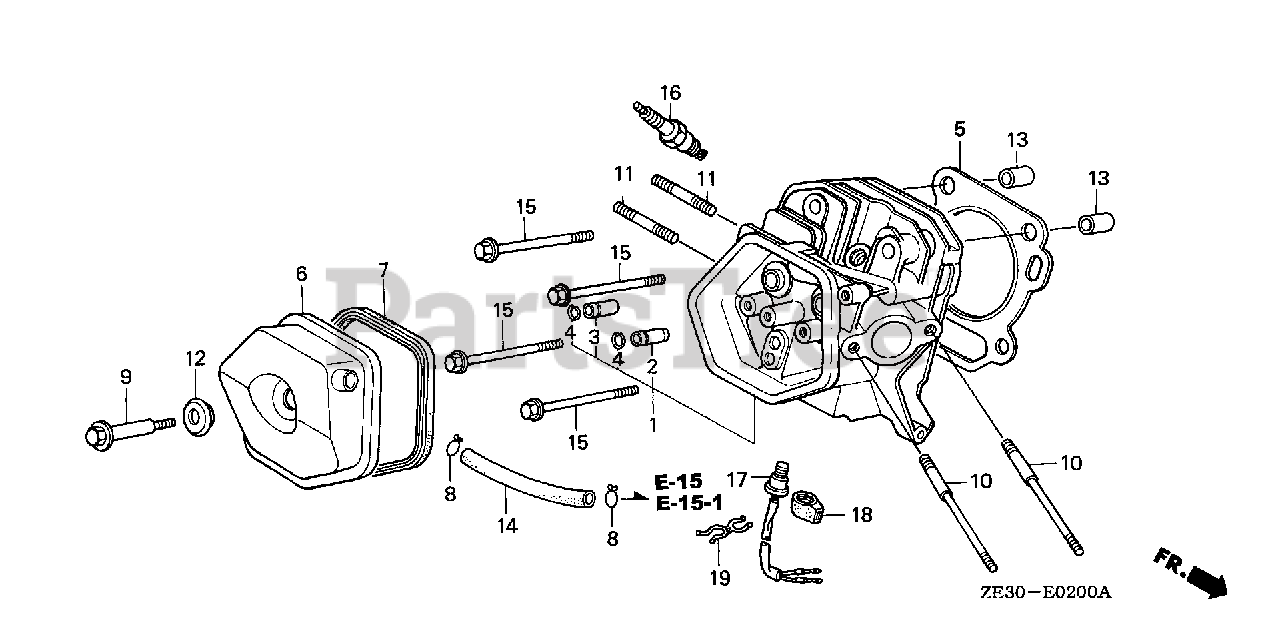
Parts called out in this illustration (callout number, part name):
1	CYLINDER HEAD
1	CYLINDER HEAD (NOT AVAILABLE)
2	GUIDE, VALVE (OVER SIZE)
3	GUIDE, EX. VALVE (OVER SIZE)
4	CLIP, VALVE GUIDE
5	GASKET, CYLINDER HEAD
6	COVER, HEAD
7	GASKET, HEAD COVER
8	CLIP, BREATHER TUBE
9	BOLT, HEAD COVER
10	BOLT, STUD (8X111)
11	BOLT, STUD (8X34)
11	BOLT, STUD (8X47)
12	WASHER, HEAD COVER
13	PIN, DOWEL (12X20)
14	TUBE, BREATHER
14	TUBE, BREATHER (NOT AVAILABLE)
15	BOLT, FLANGE (10X80)
16	SPARK PLUG (BPR6ES-11)
16	SPARK PLUG (W20EPR-U11)
17	SWITCH, THERMO
18	CAP, THERMO SWITCH
19	CLIP, WIRE HARNESS
